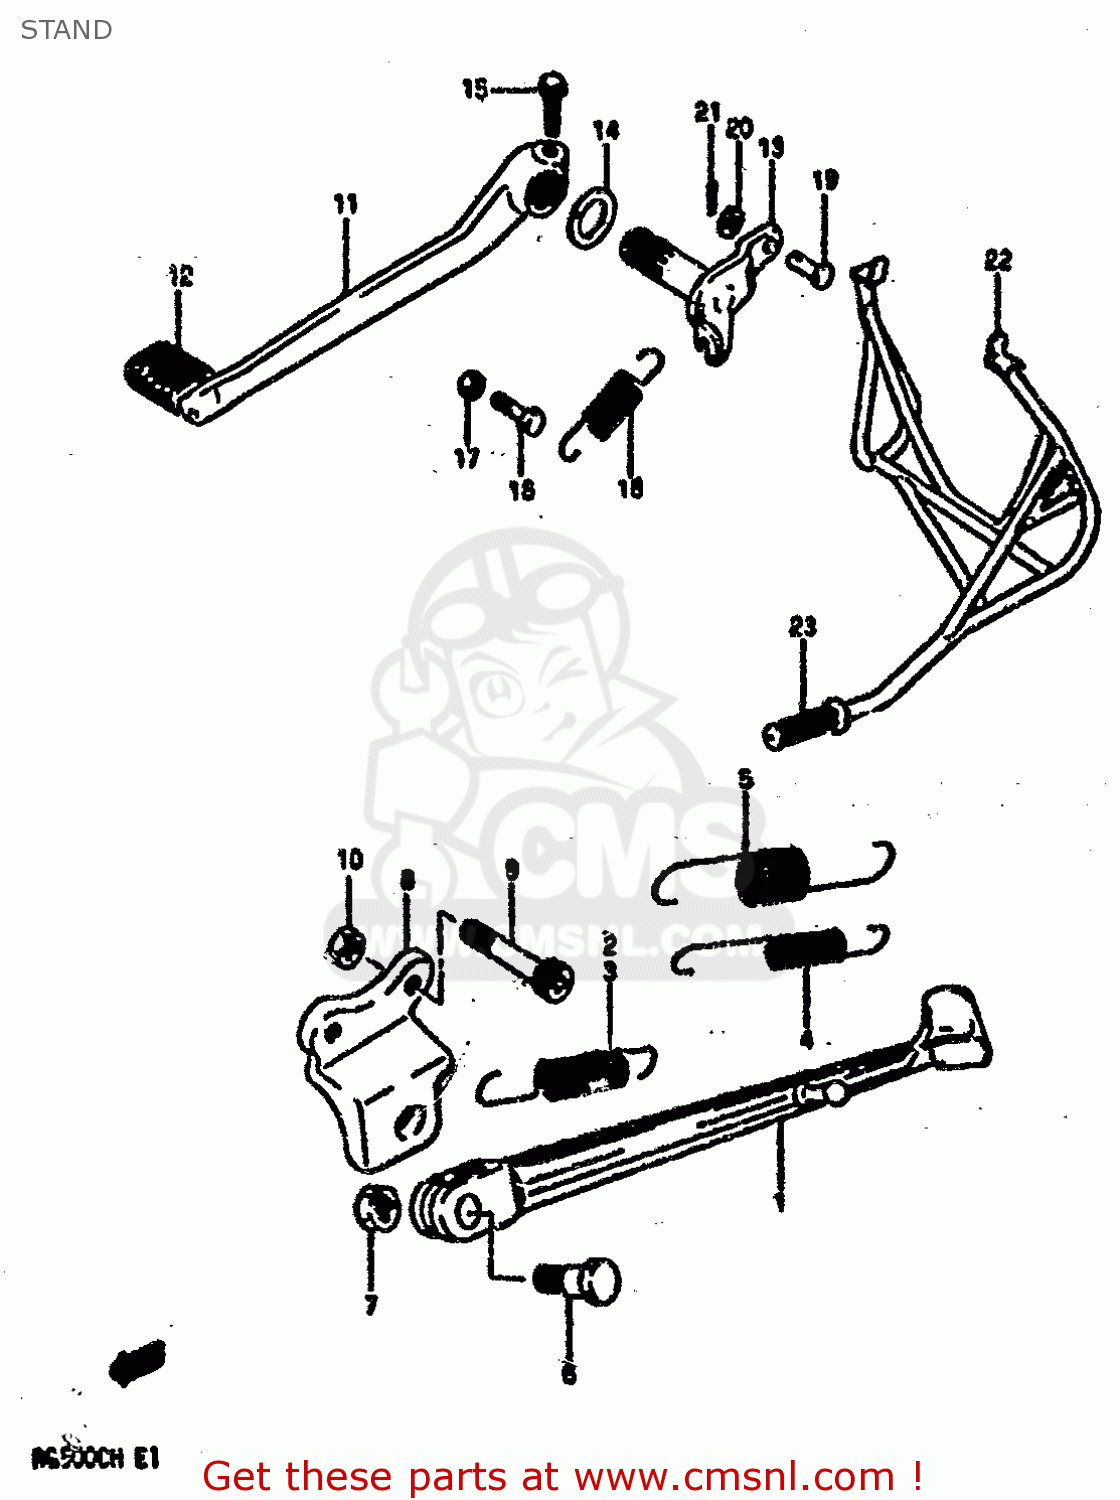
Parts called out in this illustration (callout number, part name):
1	STAND,PROP
2	SPRING
3	SPRING
4	SPRING
5	SPRING
6	BOLT L:30
7	NUT
8	BRACKET,PROP STAND
9	BOLT
10	NUT 8MM
11	PEDAL,BRAKE
12	RUBBER,BRAKE PEDAL
13	ARM,BRAKE ROD
14	WASHER,BRAKE PEDAL
15	BOLT
16	BOLT 6X16
17	NUT
18	SPRING
19	PIN
20	WASHER
21	PIN
22	STAND ASSY,REAR
23	GRIP,L
